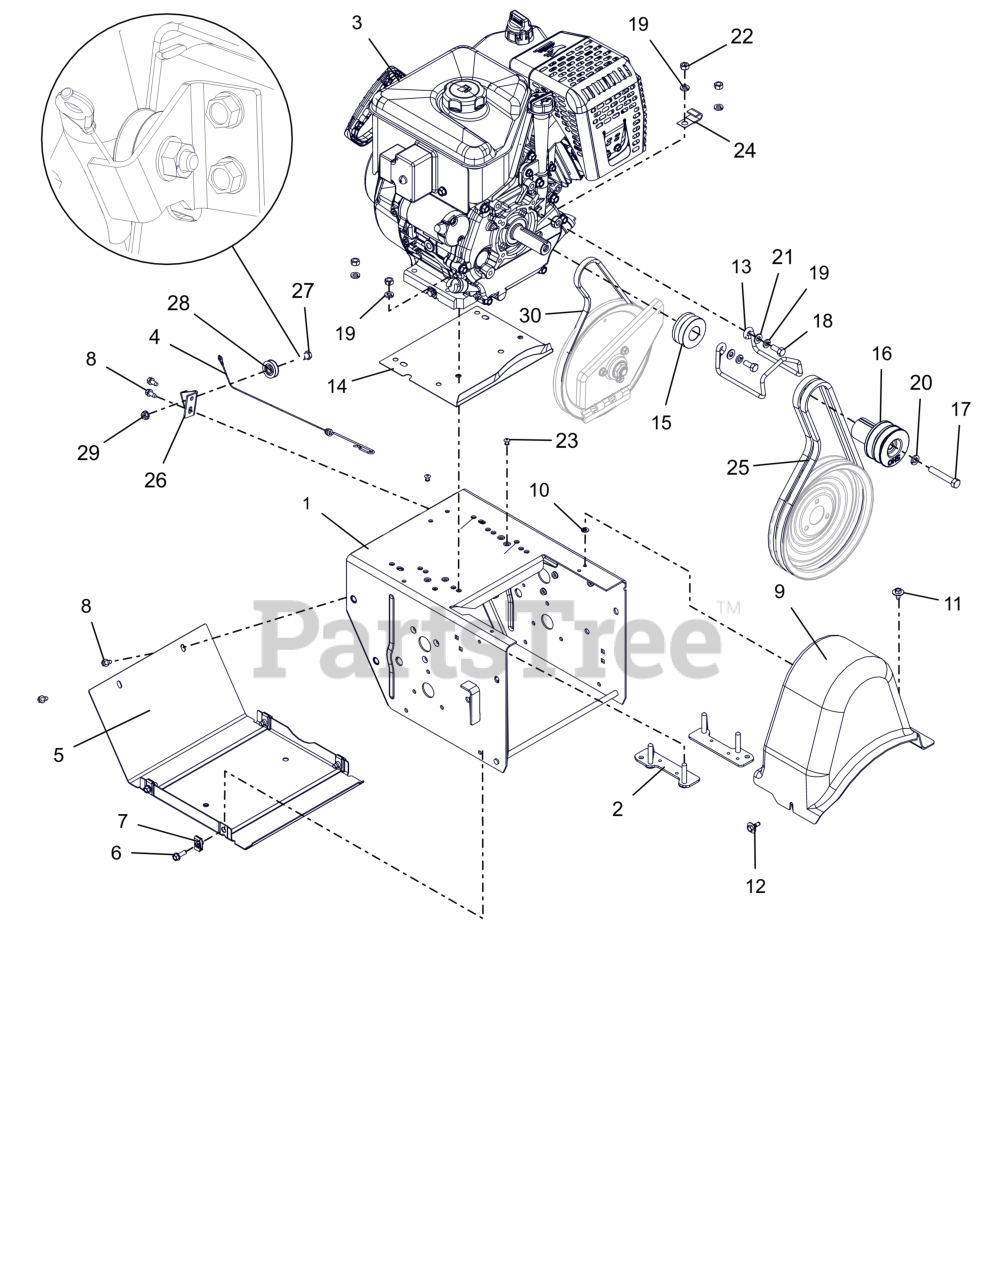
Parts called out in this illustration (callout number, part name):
1	FRAME, MAIN-DELUXE(WELDMENT)
2	STRAP, ENGINE-MEDIUM BLOCK
3	ENGINE, AX306 GEN3 240V60W
4	CABLE, LOWER TRACTION,SS & PRO
5	COVER, BOTTOM
6	BLT, HWH .25-20X.75 G5 ZCC
7	NUT-RTNR .25-20X.56
8	SCR-TAP .25-20X.50 HWH ZCC
9	COVER, BELT-LARGE
10	NUT-PUSH .25X.50 O.D.
11	SCR, TAP .25-20X.50 LG HWH ZCC
12	SCR-TAP .25-20X.5 CAPTIVE
13	FINGER, BELT
14	BAFFLE, WATER - LARGE BLOCK
15	SHEAVE, TRACTION (KEYLESS)
16	SHEAVE,ATTACHMENT-SHO 2 GRV
17	BLT, HEX .38-24X2.25 G5 ZCC
18	BLT, HEX .31-24X.750 G5 ZCC
19	WSHR, LK-HVY .312X.097 ZCC
20	WSHR,LK-REG .375X.094 ZCC
21	WSHR,FLT .344X.688X.065 ZCC
22	NUT, HEX .312-18 ZCC
23	RVT, POP .1875 ZCC
24	J-CLAMP
25	V-BELT, HA-RAW EDGE (SET)
26	BRACKET, CABLE PULLEY
27	BOLT, SHLDR -.375 X .375 X .25-20
28	PULLEY, CABLE
29	NUT-LK-TOP-FLG .250-20 GF ZCC
30	V-BELT, 3L-WRAPPED
